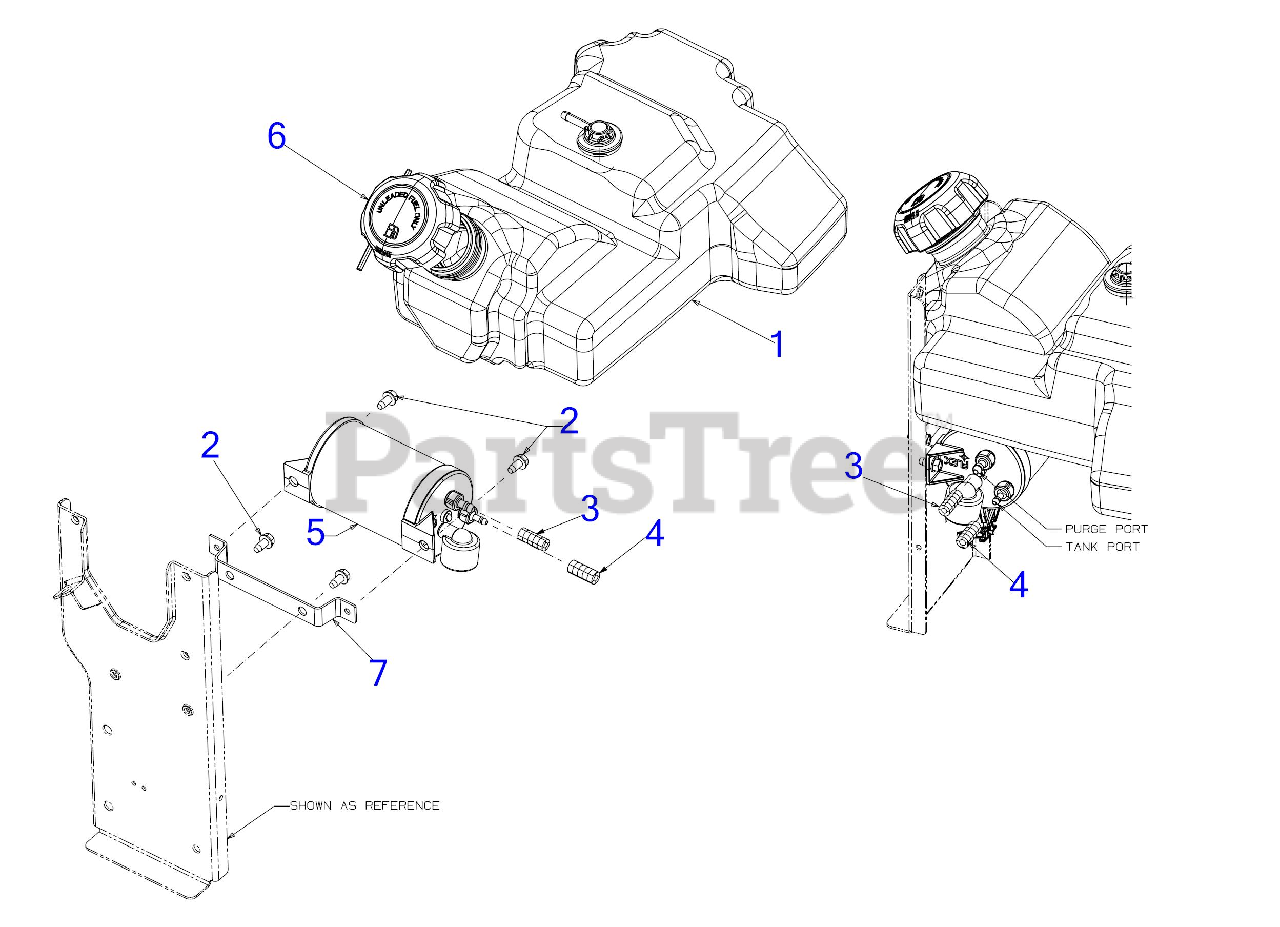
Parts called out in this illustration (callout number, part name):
1	FUEL TANK ASSEMBLY
2	SCREW 1/4-20 X.500
3	FUEL HOSE LO PERMEATION 3/16 WHITE
4	FUEL HOSE LO PERMEATION 7/32 YELLOW
5	CARBON CANISTER
6	FUEL CAP W/TETHER
